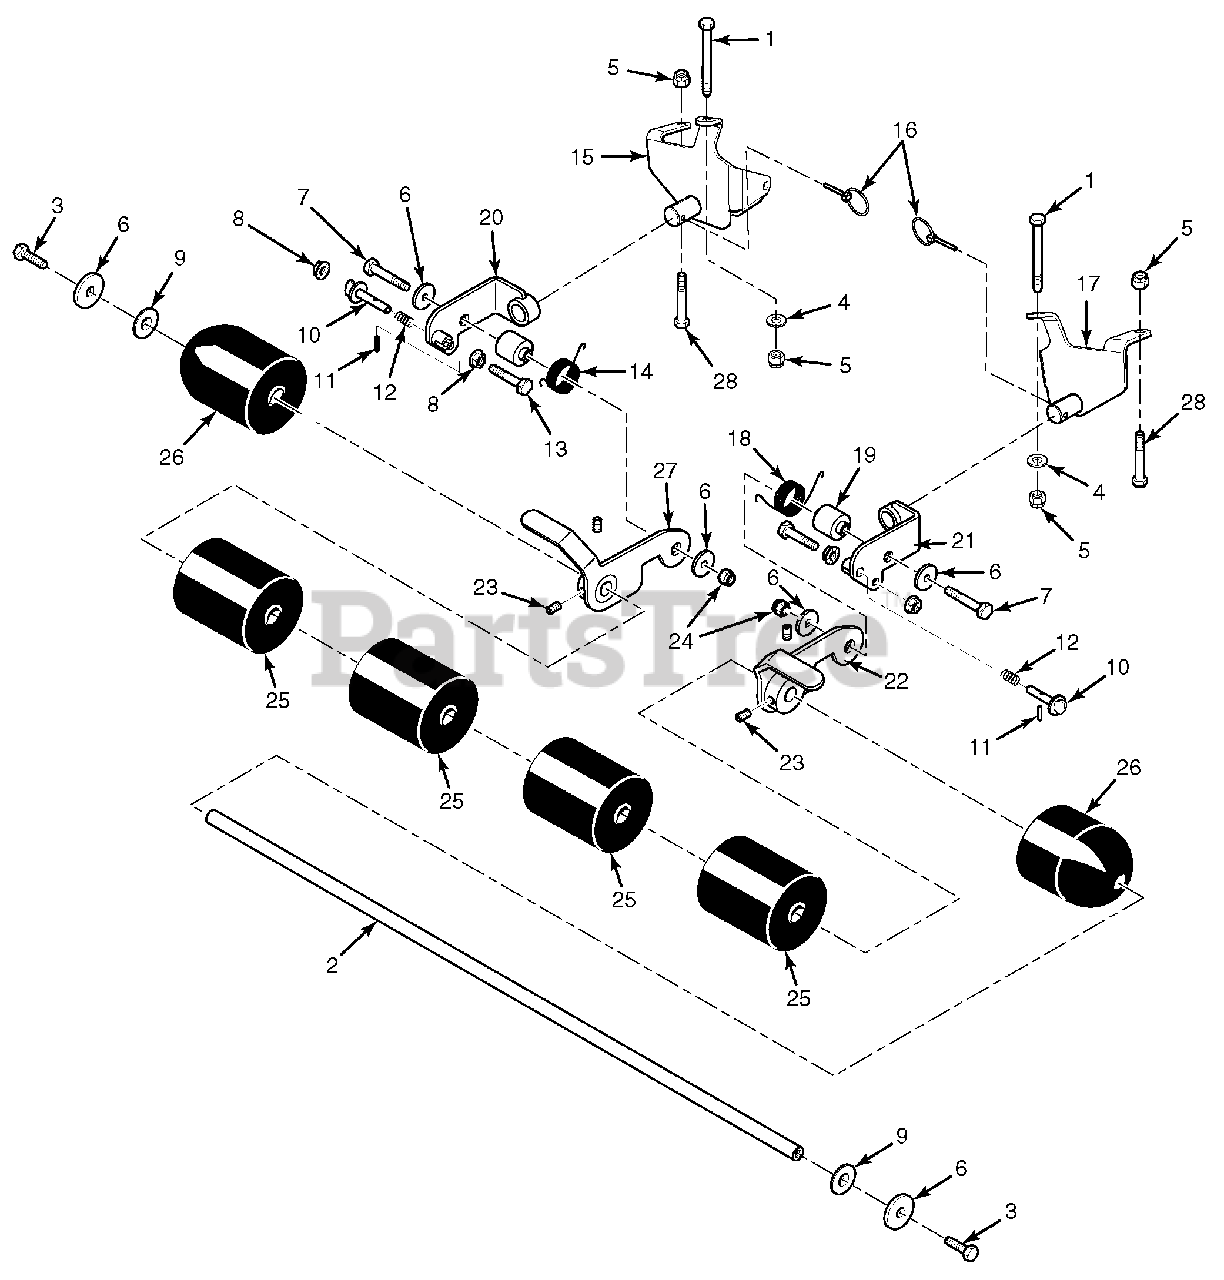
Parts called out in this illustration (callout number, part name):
1	Bolt, Hex Head 5/16-18 x 2-1/2" - SZL
1	Bolt, Hex Head 5/16-18 x 5-1/2" - SFZ
2	Roller Shaft
3	Bolt, Hex Head 3/8-16 x 1" (Special Lock)
4	Flatwasher, 5/16-.378 x .875 x .083
5	Nut, Elastic Stop 5/16-18
6	Flatwasher, 3/8-.406 x 1-1-1/2 x 7 Gauge
7	Bolt, Hex Head 3/8-16 x 2-3/4"
8	Nut, Serrated Flange 3/8-16
9	Flatwasher, 3/4-.812 x 1-3/8 x .100
10	Pin, Lift Latch
11	Pin, Slotted Spring 5/32" x 7/8"
12	Spring, Lock Pin
13	Bolt, Hex Head 3/8-16 x 2-1/2"
14	Spring, Torsion LH
15	Mounting Bracket Weldment, LH - SZL
15	Mounting Bracket Weldment, LH - SFZ
16	Quick Pin, .188 Dia.
17	Mounting Bracket Weldment, RH - SZL
17	Mounting Bracket Weldment, RH - SFZ
18	Spring, Torsion RH
19	Hub, Striper
20	Pivot Weldment, LH
21	Pivot Weldment, RH
22	Hinge Weldment, RH
23	Set Screw, 3/8-16 x 1/2"
24	Nut, Elastic Stop 3/8-16
25	Wheel, Striper
26	Wheel, Striper End
27	Hinge Weldment, LH
28	Bolt, Hex Head 5/16-18 x 3-1/4"
